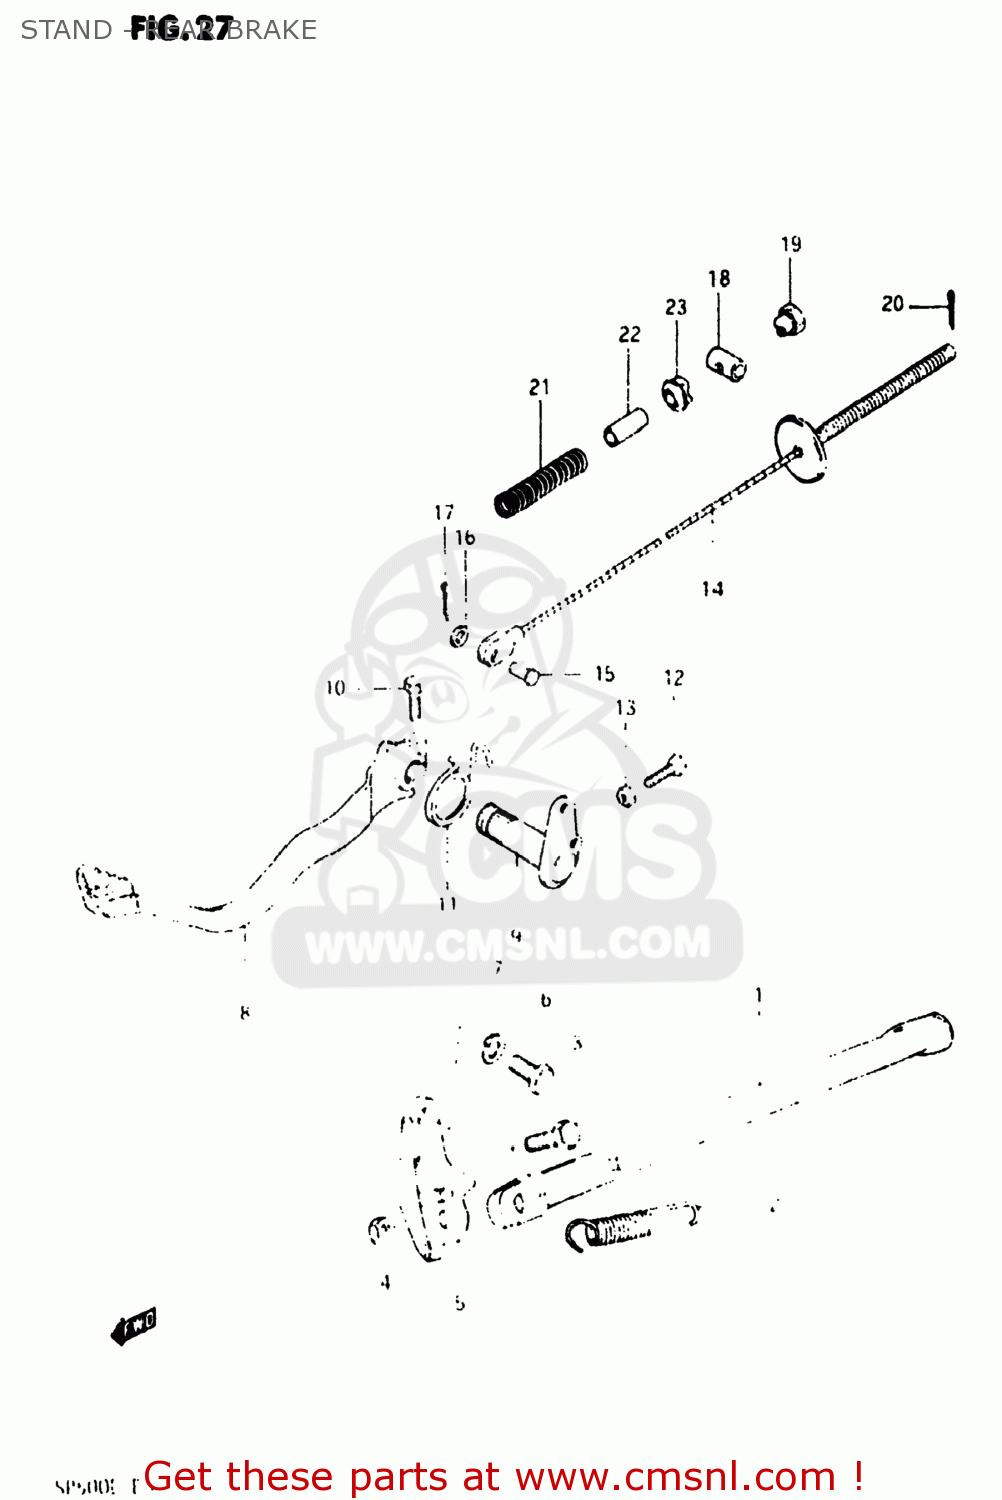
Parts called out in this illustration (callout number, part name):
1	STAND,SIDE
2	SPRING
3	BOLT(10X30)
4	NUT
5	BRACKET,PROP STAND
6	BOLT(10X19)
7	LOCK WASHER
8	PEDAL,BRAKE
9	ARM,BRAKE PEDAL
10	BOLT
11	SPRING
12	BOLT(6X23)
13	NUT
14	CABLE,RR BRAKE
15	PIN(L:17.5)
16	WASHER
17	PIN
18	PIN,BRAKE CABLE ADJUSTER
19	NUT (6MM)
20	PIN
21	SPRING
22	CUSHION,FR GRILLE,UPPER
23	CUSHION
